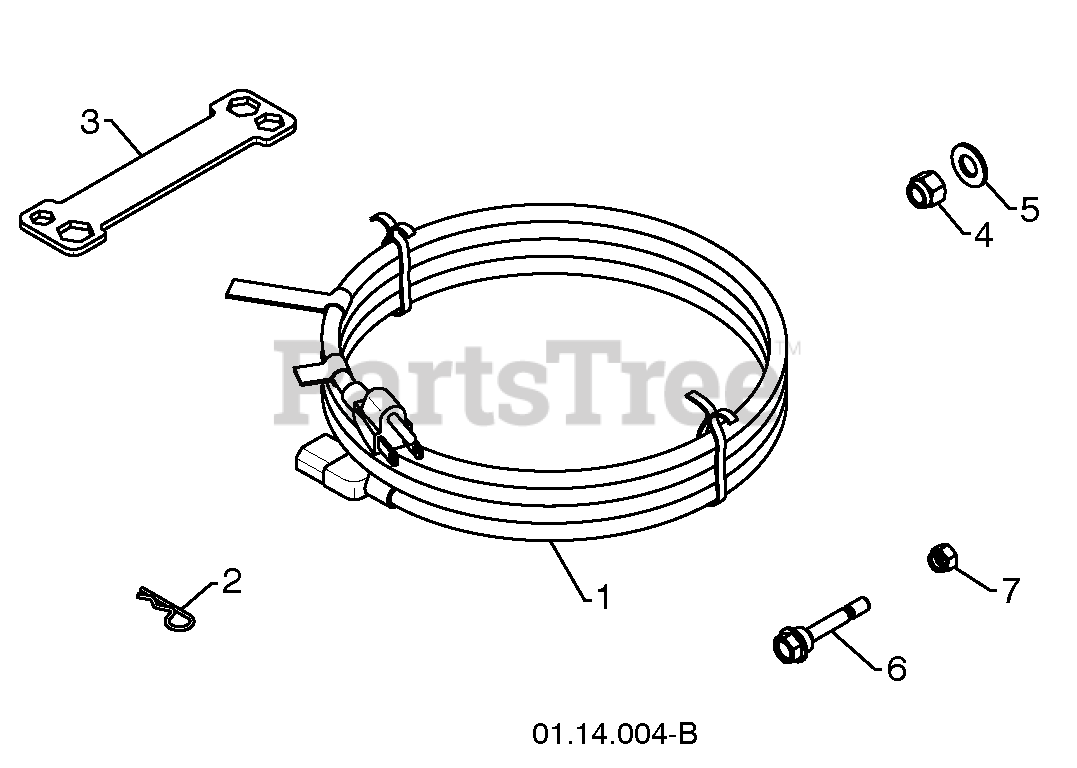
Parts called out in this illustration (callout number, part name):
1	POWER CORD
2	RETAINER PIN
3	WRENCH
4	LOCKNUT 3/8-16
5	WASHER 3/8
6	SHEAR BOLT 1/4-20 X 1-3/4
7	LOCKNUT 1/4-20
